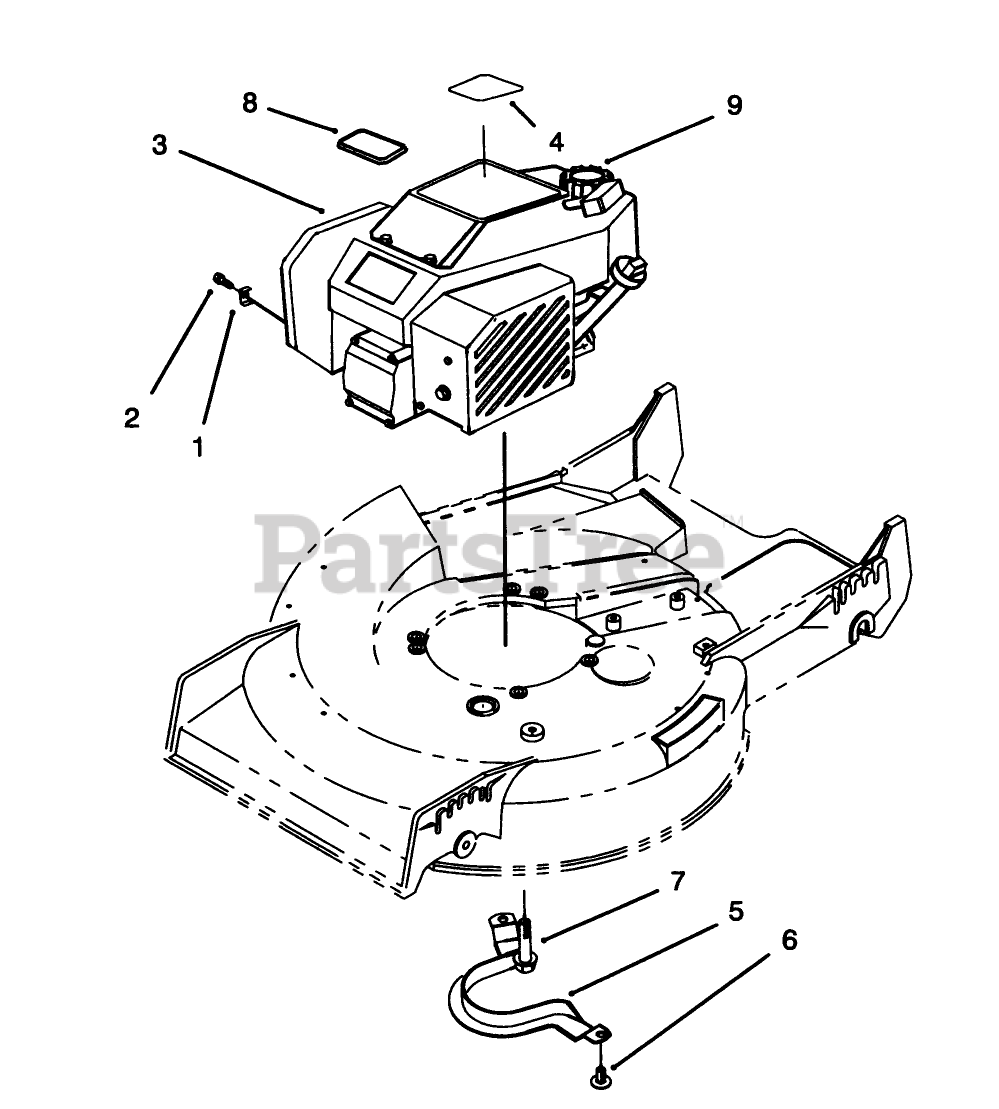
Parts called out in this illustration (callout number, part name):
1	CLAMP-CASING
2	Screw
3	Engine (Incl.Ref. #4 & 8)
4	DECAL - ENGINE
5	Guide-Belt
6	SCREW-HWH
7	SCREW-HWH
8	PLATE-LOGO
9	GAS CAP ASM
